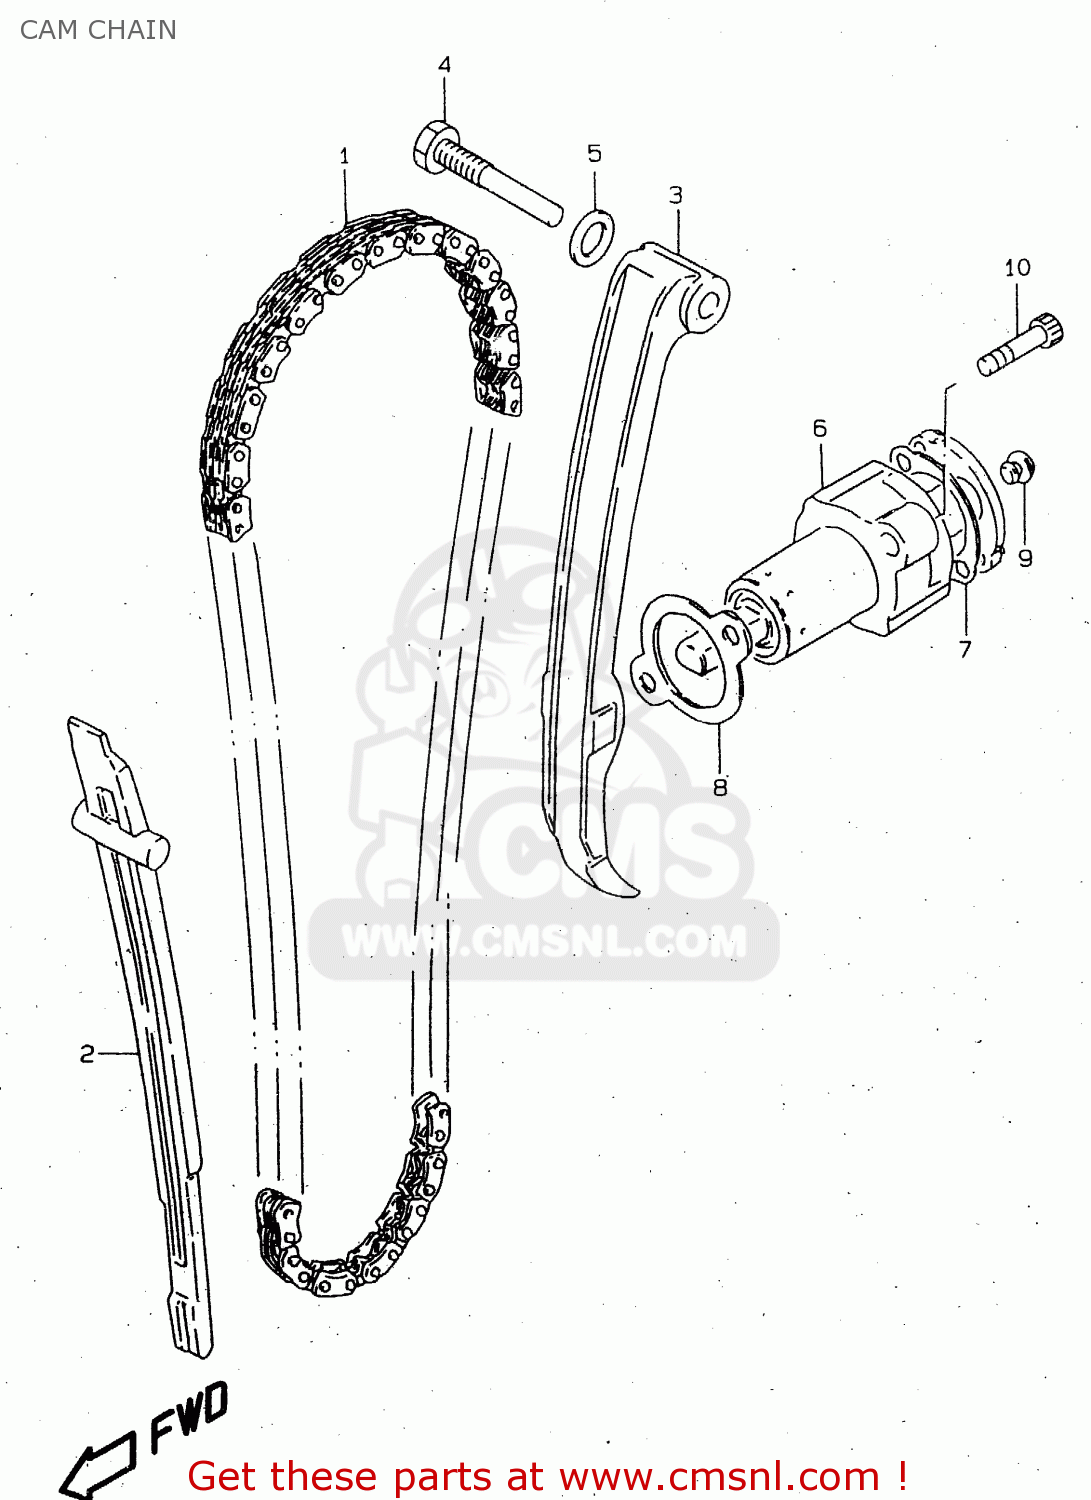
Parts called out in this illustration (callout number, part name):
1	CHAIN,CAMSHAFT DRIVE
2	GUIDE,CAM CHAIN
3	TENSIONER,CAM CHAIN
4	BOLT,CAM CHAIN TENSIONER
5	GASKET 8.2X14X1 (NAS)
6	ADJUSTER ASSY,TENSIONER
7	GASKET,ADJUSTER CAP (NAS)
8	GASKET,TENSIONER ADJUSTER (NAS)
9	PLUG,ADJUSTER
10	BOLT
